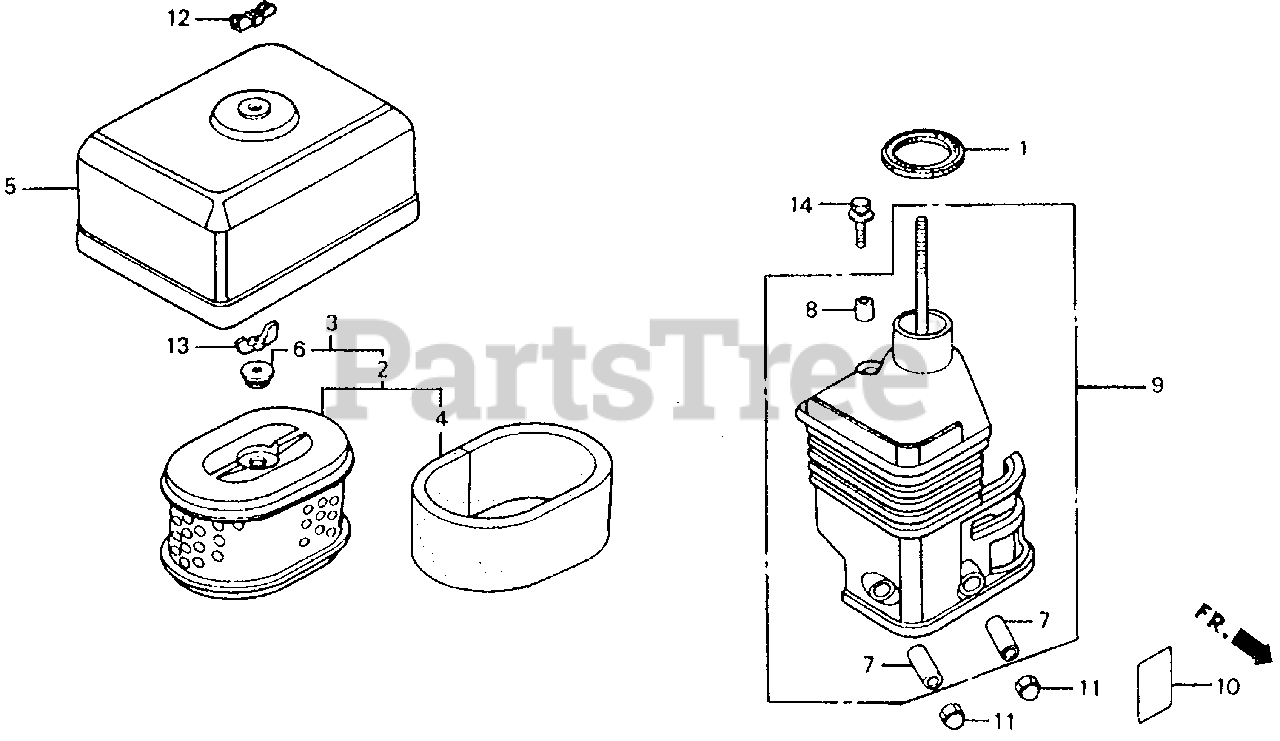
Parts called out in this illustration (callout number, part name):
1	GASKET, ELBOW
3	ELEMENT, AIR CLEANER (DUAL)
4	FILTER (OUTER)
5	COVER, AIR CLEANER (DUAL)
6	GROMMET, AIR CLEANER
7	COLLAR, AIR CLEANER
8	COLLAR B, AIR CLEANER
9	ELBOW, AIR CLEANER
10	MARK, CHOKE
11	NUT, CAP (6MM)
12	WINGNUT, AIR CLEANER COVER
13	WINGNUT, TOOL BOX SETTING
14	BOLT-WASHER (6X20)
